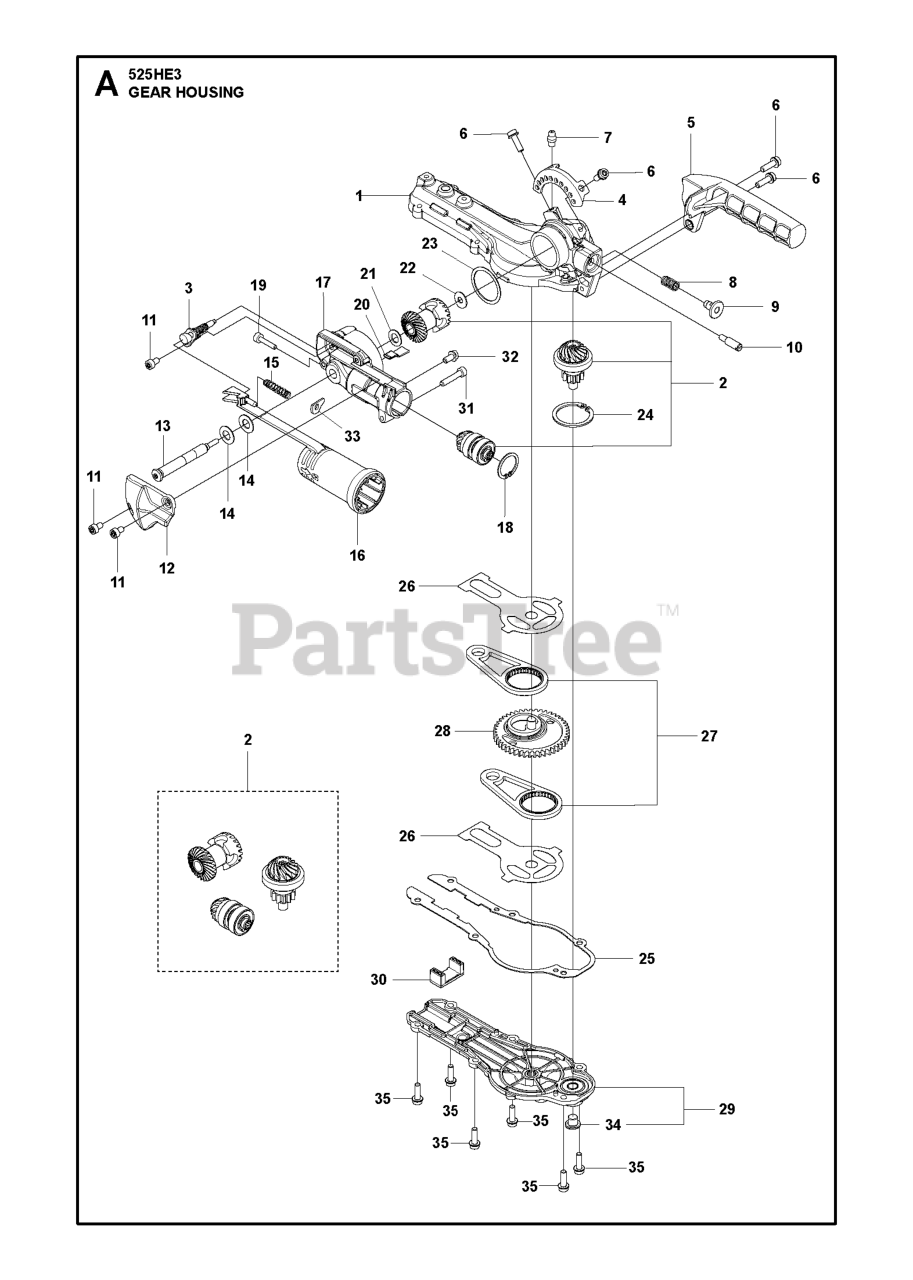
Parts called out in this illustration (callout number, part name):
7	GREASE NIPPLE
18	RETAINING RING
19	SCREW ITXSCM
24	RETAINING RING SGH 35
28	GEAR WHEEL ASSY
30	SEALING PLASTIC
31	SCREW
32	SCREW ITXSCM
33	Spacers
34	SCREW PLUG HEXALOBULAR SOCKET
